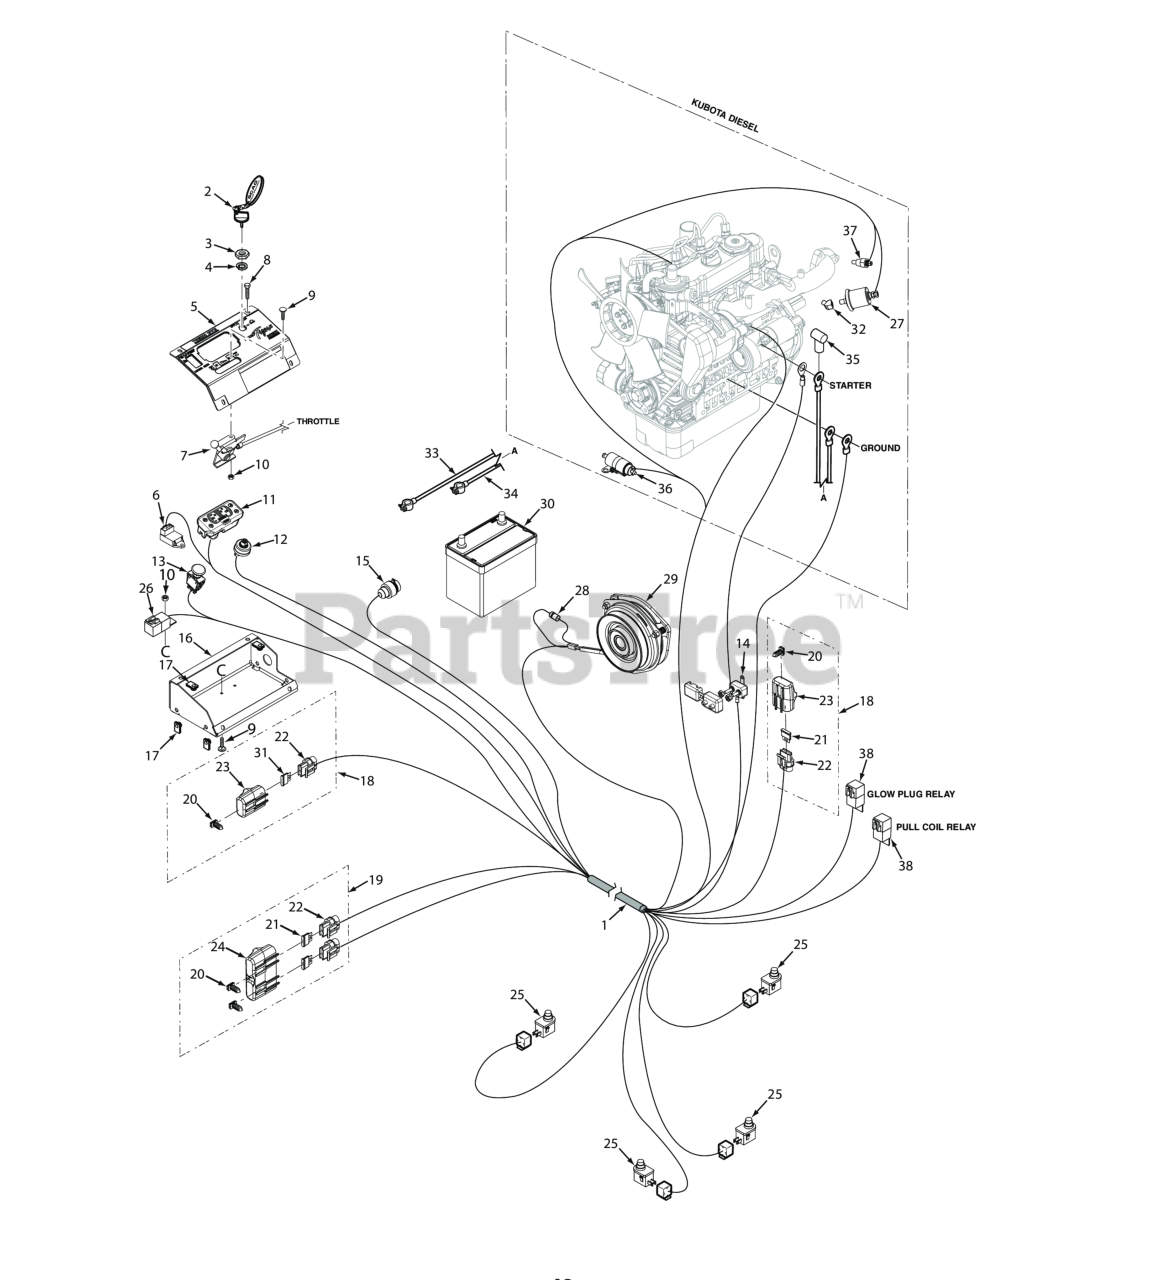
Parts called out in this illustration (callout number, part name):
1	Wire Harness, STTII-25KBD
2	Key, Assembly w/Fob
3	Nut, 5/8-32 Special
4	LOCK WASHER, 5/8" INTERNAL TOOTH
5	Instrument Panel w/Decal
6	Timer, Glow Plug
7	Cable, Control (Throttle)
8	Bolt, Hex Head Serrated Flange 1/4-20 x 3/4"
9	Bolt, Carriage #10-24 x 1/2"
10	Nut, Elastic Stop #10-24
11	Tiger Eye, Cluster Gauge
12	KEY SWITCH(INCLUDES MOUNTING HARDWARE)
13	Switch, PTO - 10 Amp
14	50 Amp Breaker
15	Power Plug, 12V
16	Base, Instrument Panel
17	Bolt, Hex Head 3/8-16 x 1"
18	Single Fuse Assy., Excluding Fuse
19	Double Fuse Assy.
20	Clip, Fuse Holder
21	FUSE, 20 AMP BLADE TYPE AUTOMOTIVE
22	Fuse Holder Assembly
23	Cover, Sealed Single
24	Cover, Sealed Double
25	Switch, Interlock, Normally Open
26	Relay, 12V 40 AMP Standard
27	Sender Unit, Oil Pressure
28	Diode, 600V 6 Amp
29	Clutch Assembly, GT3.5 (Diesel Engine)
30	Battery, 525 CCA
31	Fuse, 5 Amp
32	Elbow, 45 Degree Street
33	Battery Cable, 14" Red w/Braid
34	Battery Cable, 21" Black
35	Boot, Positive Battery Terminal
36	Solenoid, Fuel Shut-Off
37	Temperature Sensor, Engine Coolant
38	Relay, 12V 40 AMP Hi Capacity
